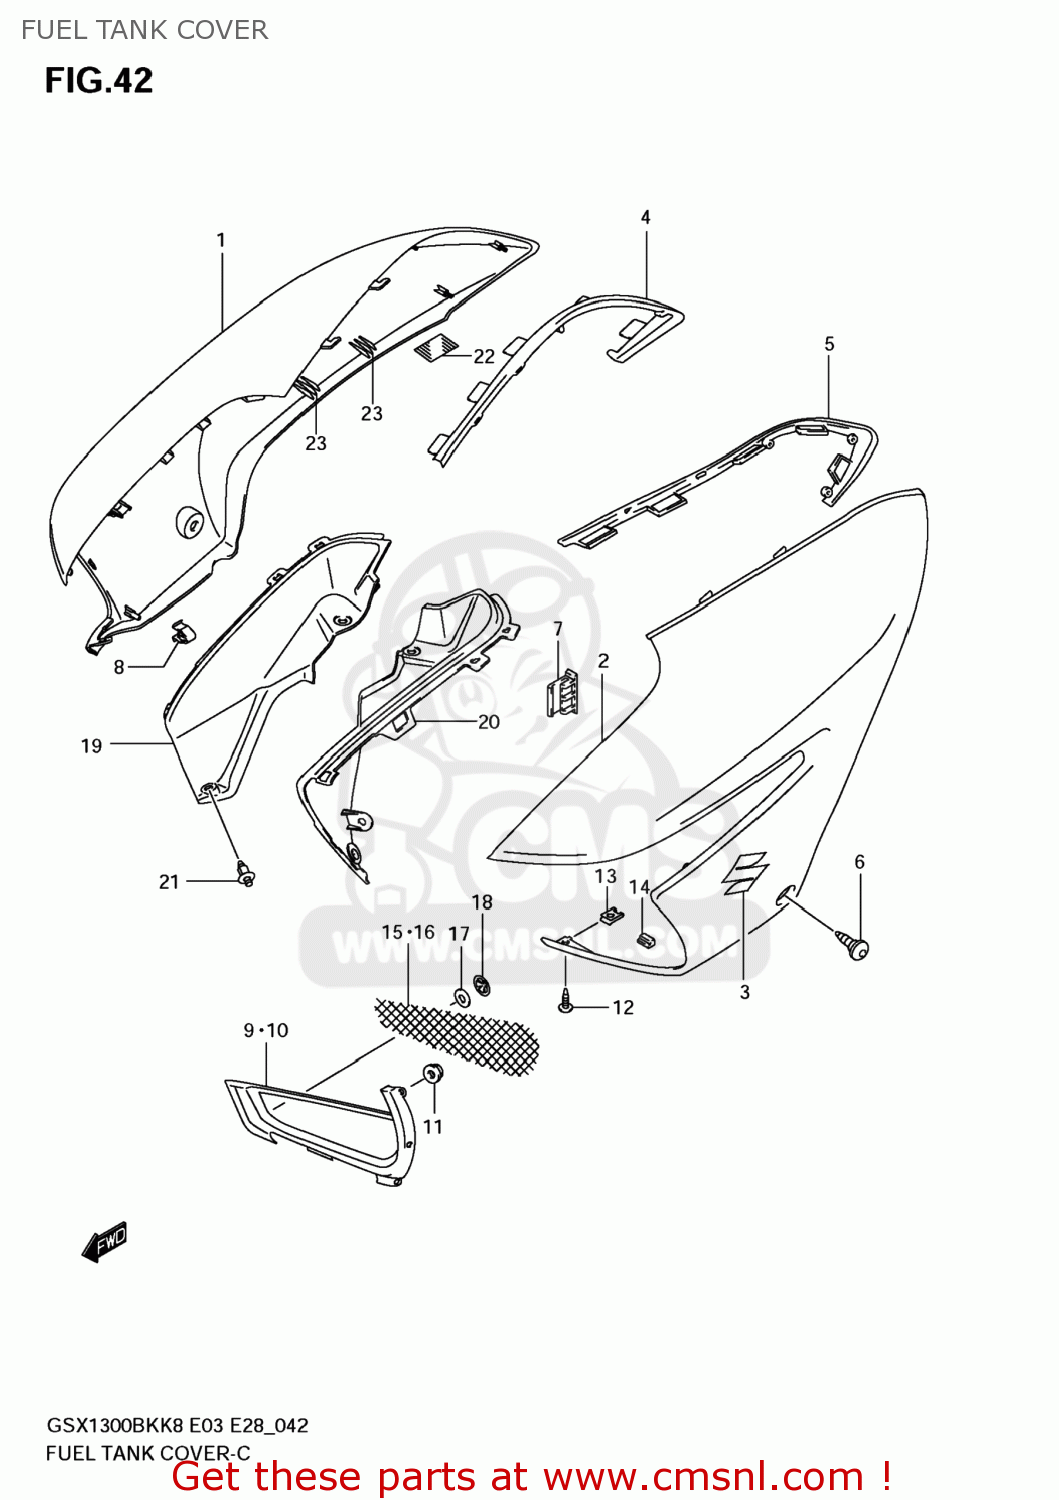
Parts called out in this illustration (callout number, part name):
1	COVER,FUEL TANK,R
2	COVER,FUEL TANK,L
3	EMBLEM,S
4	CUSHION,FUEL TANK COVER,R
5	CUSHION,FUEL TANK COVER,L
6	SCREW(5X13)
7	GUIDE,FUEL TANK COVER
8	CLIP
9	COVER,INTAKE,R
10	COVER,INTAKE,L
11	NUT
12	SCREW
13	NUT
14	CUSHION,FUEL TANK COVER
15	NET,INTAKE,R
16	NET,INTAKE,L
17	CUSHION
18	NUT
19	COVER,FUEL TANK FR,R
20	COVER,FUEL TANK FR,L
21	CLIP
22	FASTENER
23	CUSHION,FUEL TANK COVER
